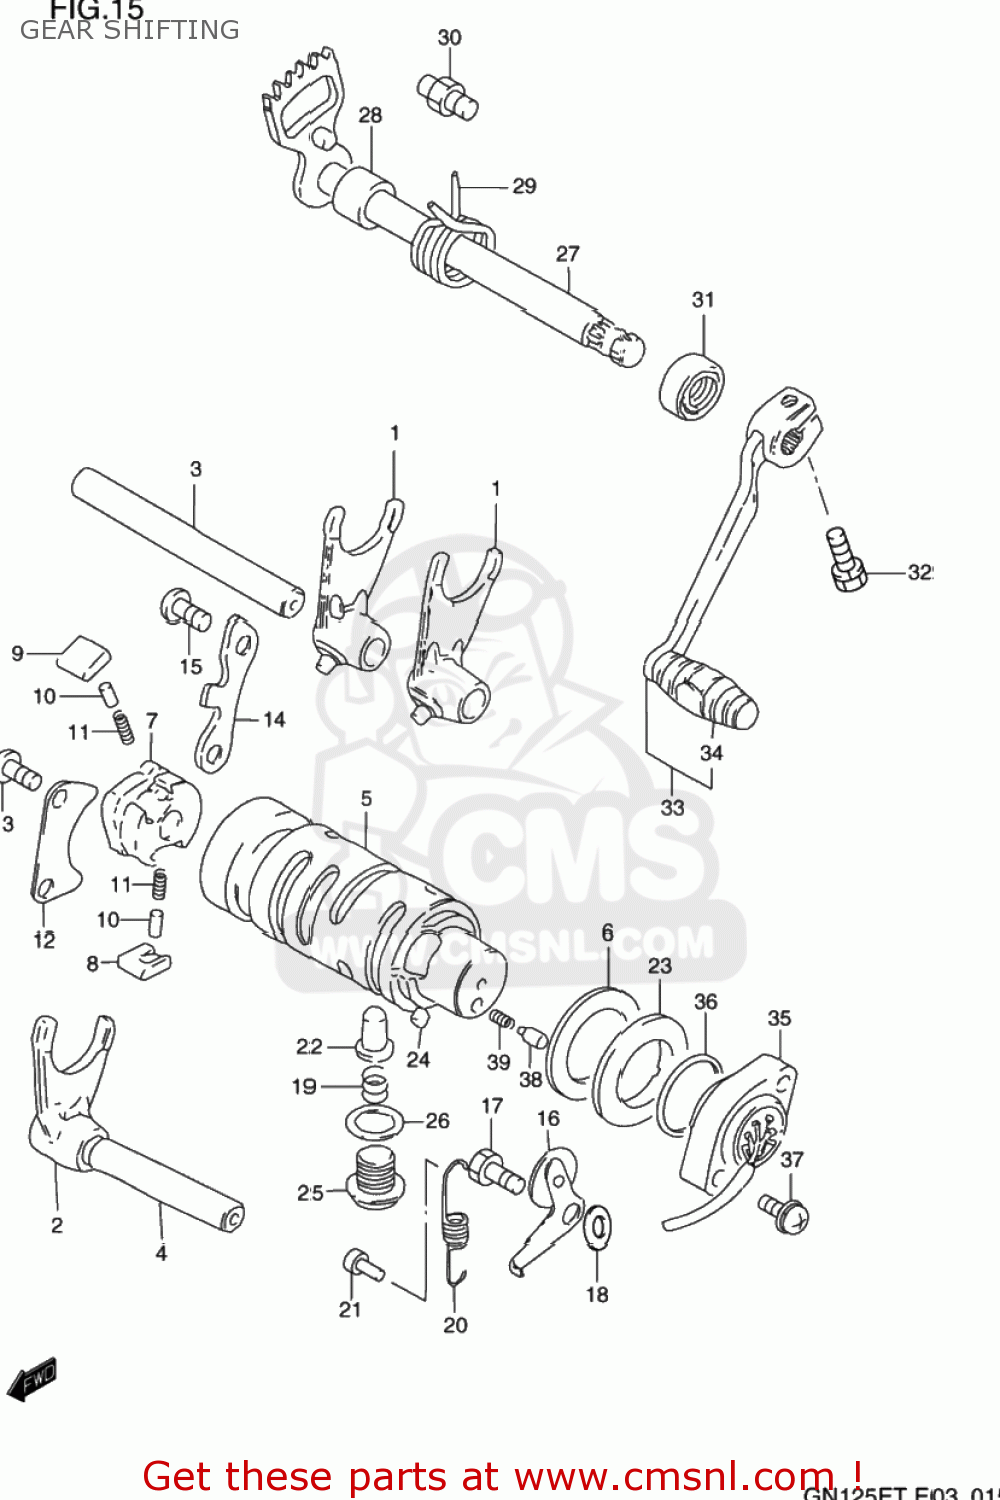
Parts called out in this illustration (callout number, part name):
1	FORK,GEAR SHIFT NO.2
2	FORK,GEAR SHIFT NO.3
3	SHAFT,GEAR SHIFT FORK
4	SHAFT,GEAR SHIFT FORK
5	CAM,GEAR SHIFT
6	WASHER,THRUST
7	GEAR,GEARSHIFT CAM DRIVE
8	PAWL,GEAR SHIFT NO.1
9	PAWL,GEAR SHIFT NO.2
10	PIN(5X8)
11	SPRING
12	LIFTER,GEAR SHIFT POLE
13	SCREW
14	GUIDE,GEAR SHIFT CAM
15	SCREW
16	STOPPER,GEAR SHIFTING
17	BOLT
18	WASHER
19	SPRING
20	SPRING
21	RIVET
22	STOPPER,GEAR SHIFT CAM NO.2
23	PLATE,GEAR SHIFT CAM STOPPER
24	PIN
25	PLUG(14X12)
26	GASKET(14X19.2X2) (NAS)
27	SHAFT,GEAR SHIFT
28	SPACER(12X20X15.3)
29	SPRING
30	STOPPER,GEAR SHIFT CAM
31	OIL SEAL
32	BOLT
33	LEVER ASSY,GEAR SHIFT
34	RUBBER,GEAR SHIFT PEDAL
35	BASE ASSY,GEAR SHIFT TERMINAL
36	O-RING (D:2.4 ID:26.2)
37	SCREW
38	PIN(5X15.5)
39	SPRING
